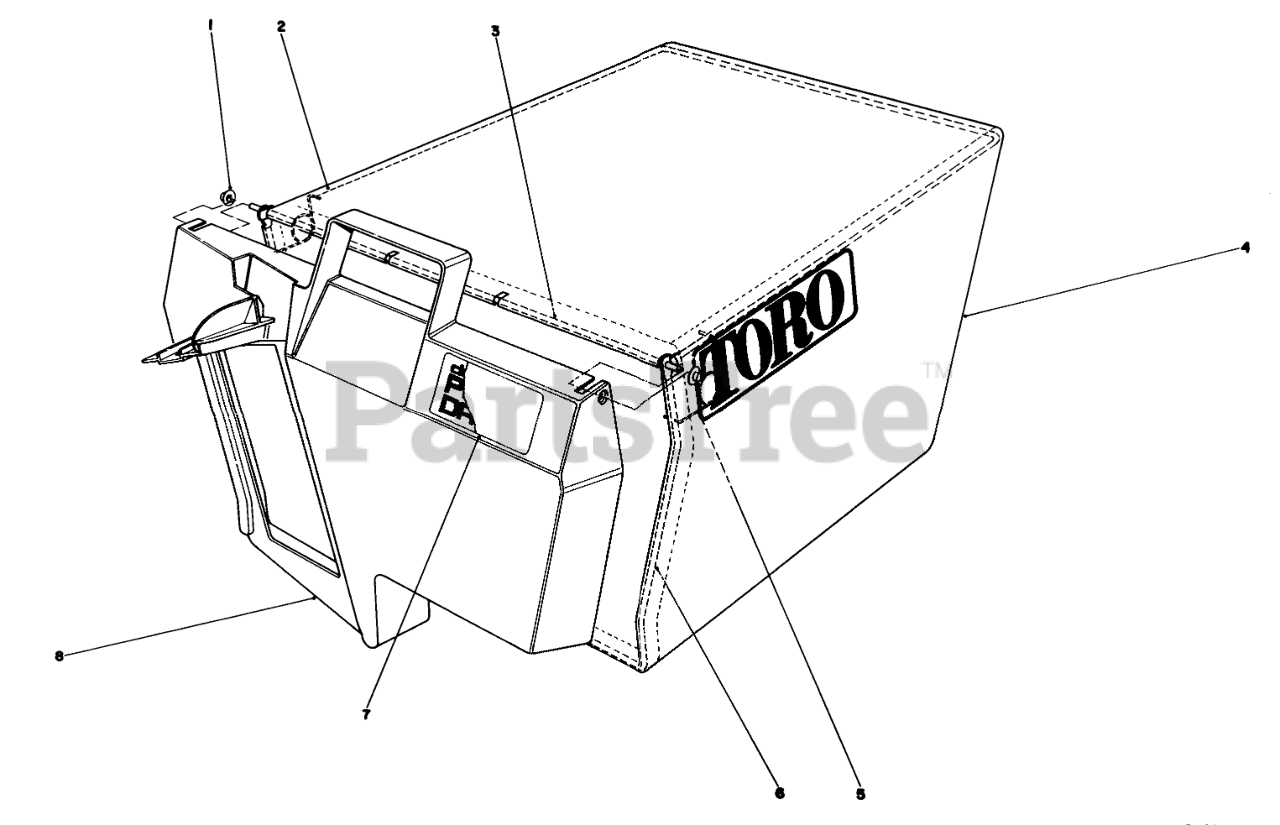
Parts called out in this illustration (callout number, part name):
1	NUT-PUSH
2	FRAME-BAG, UPPER
3	HINGE-DOOR, BAG
4	BAG-GRASS
5	SPRING
6	FRAME-BAG
7	BAG DOOR DECAL
8	DOOR-BAG
